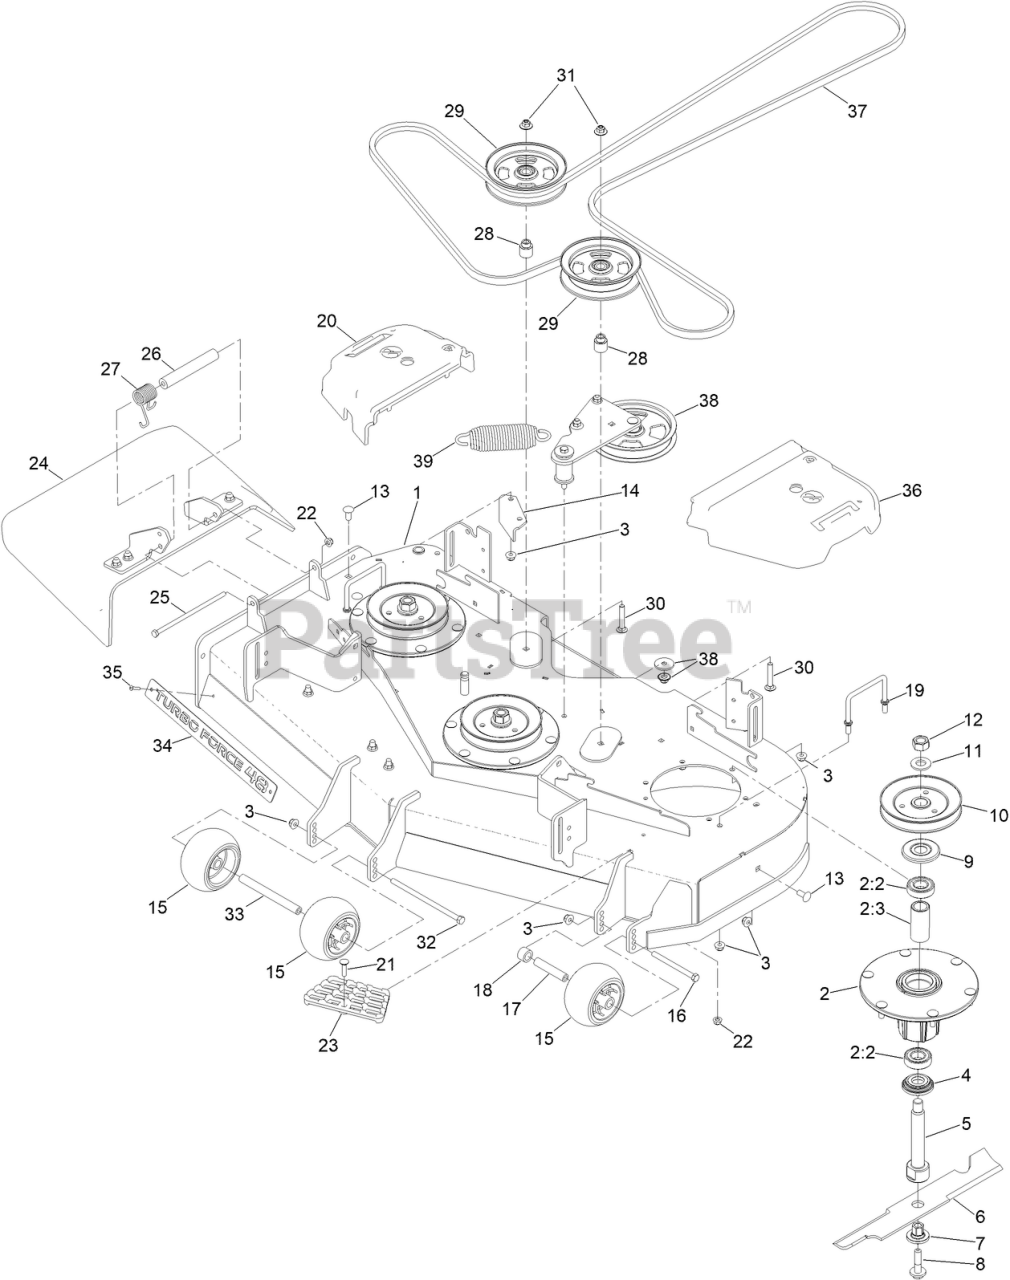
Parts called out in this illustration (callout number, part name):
1	DECK DECAL ASM
2	SPINDLE ASM
2:2	BEARING-BALL
2:3	SPACER-BEARING
3	NUT-HF, NI
4	GUARD-BOTTOM
5	SHAFT-SPINDLE
6	BLADE-16.50 HIGH FLOW
7	BUSHING-HEX
8	SCREW-SEMS
9	GUARD-BEARING, TOP
10	SHEAVE,BLADE DRIVE 5.91
11	WASHER
12	NUT-HEX
13	SCREW-CARR
14	BAFFLE-DISCHARGE
15	ROLLER-SCALP, ANTI
16	SCREW-HH
17	TUBE-SHAFTING
18	TUBE-SPACER
19	WIREFORM-COVER
20	COVER-BELT, RH
21	SCREW-CARR
22	NUT-HF, NI
23	STEP-DECK
24	RUBBER DEFLECTOR ASM
25	SCREW-HH
26	SPACER
27	SPRING-TORSION
28	BUSHING, IDLER
29	PULLEY-IDLER, FLAT
30	SCREW-CARR
31	NUT-FLANGE, NI
32	SCREW-HH
33	SPACER-WHEEL
34	PLATE-TURBO FORCE [BLACK]
35	RIVET-TRIFOLD
36	COVER-BELT, LH
37	BELT-V
38	IDLER ARM ASM
39	SPRING-EXTENSION
